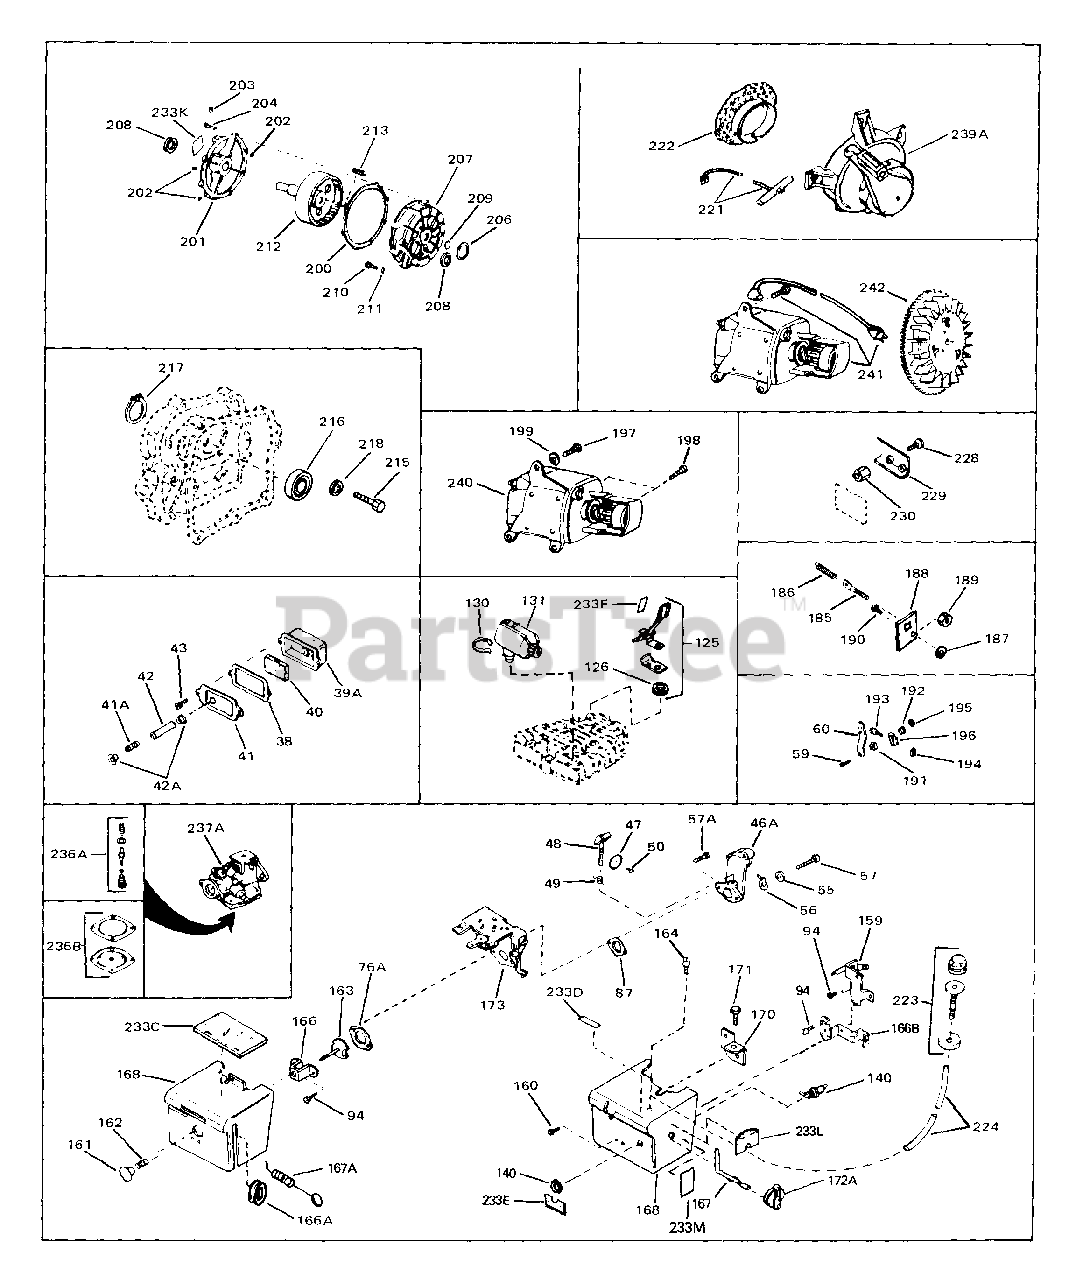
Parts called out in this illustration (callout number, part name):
5	Valve, Intake (Standard)
5	Valve, Intake (1/32" oversize)
38	Gasket, Breather
40	Element, Breather
43	Screw, Fil. hd. Sems, 10-24 x 1/2
57	Screw, Hex hd., 1/4-28 x 1
57A	Screw, Fil. hd., 1/4-28 x 2
59	Screw, Hex washer hd., 8-32 x 5/16
60	Lever, Governor
87	Gasket, Carburetor
94	Screw, Fil. hd. Sems, 10-32 x 1/2
164	Screw, Pan hd. self-tap, 10-32 x 5/16
241	Starter Motor Kit (110-120 Volt)
242	Flywheel
